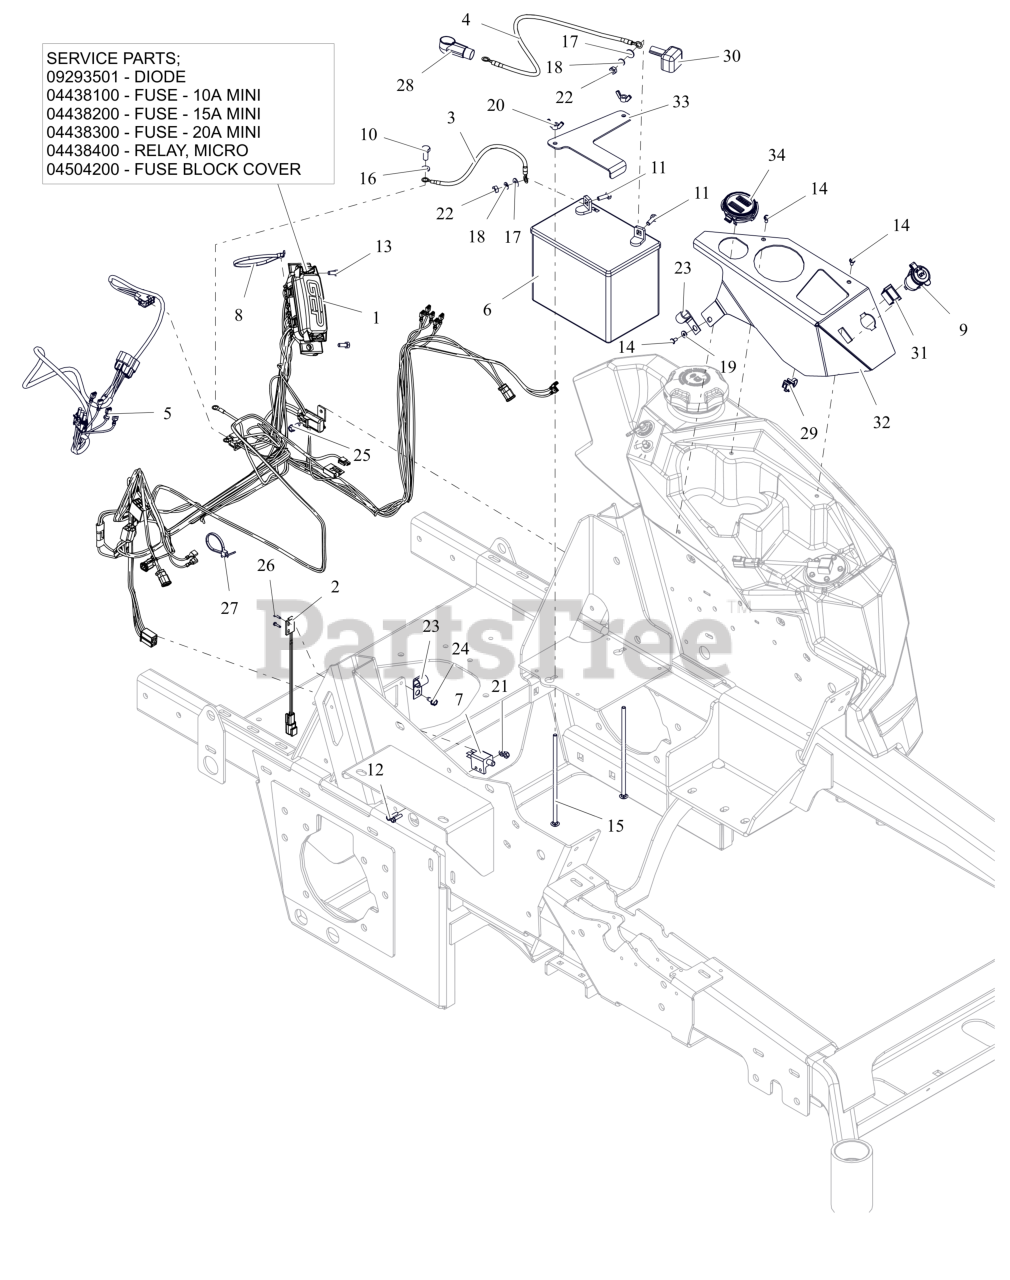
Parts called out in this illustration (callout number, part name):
1	HARNESS, ELECTRICAL 421
1	DIODE, CONNECTOR SHELL
1	FUSE,10 AMP MINI-ATC
1	FUSE,15 AMP MINI-ATC
1	FUSE,20 AMP MINI ATC
1	RELAY,MICRO5 TERML W/RESISTOR
1	COVER, HARNESS FUSE/RELAY MOD
2	SWITCH, MAGNETIC
3	CABLE, NEGATIVE BATTERY 11.5 LNG
4	CABLE, POS W/(2) .312 RING 16.0 LG
5	HARNESS, PT600 EFI ADAPTER
6	BATTERY, 300 CCA 10U1L
7	SWITCH- DOUBLE POLE N.O./N.O.
8	TIE WRAP
9	PORT, 12 VOLT POWER
10	BLT, HEX M8-1.25X20 G8.8 ZCC
11	BLT, HEX .25-20X.75 G5 ZCC
12	BLT, HWH #10-24X.75 ZCC
13	BLT, HEX M6-1X16 G8.8 ZCC
14	SCR-MCH 10-24X.38 HWHSTAINLESS
15	BTL,RHSN .250-20 X 7.5 G5 ZCC
16	WSHR,LK-REG .312X.078 ZCC
17	WSHR,FLT .281X.625X.065 ZCC
18	WSHR,LK-REG .250X.062 ZCC
19	WSHR-FL-STL .196X.50X.06 ZC120
20	NUT, LK-WING .25-20 ZCC
21	NUT-LK-NYL #10-24 G2 ZCC
22	NUT-STD .250-20 G2 ZCC
24	SCR-TAP .25-20X.50 HWH ZCC
25	SCR,TAP .25-20X.625 HWH ZCC
26	SCR-TAP #4-40X.50 HWH ZCC
27	CABLE TIE W/ TREE (.25 HOLE)
28	BOOT, .65ID POS
29	TIE, EC23 MOUNT W CABLE
30	INSULATOR
31	SWITCH,BLANK
32	PANEL, LH CONTROL (RED)
33	HOLDDOWN, BATTERY (BLACK)
34	DUAL METER
